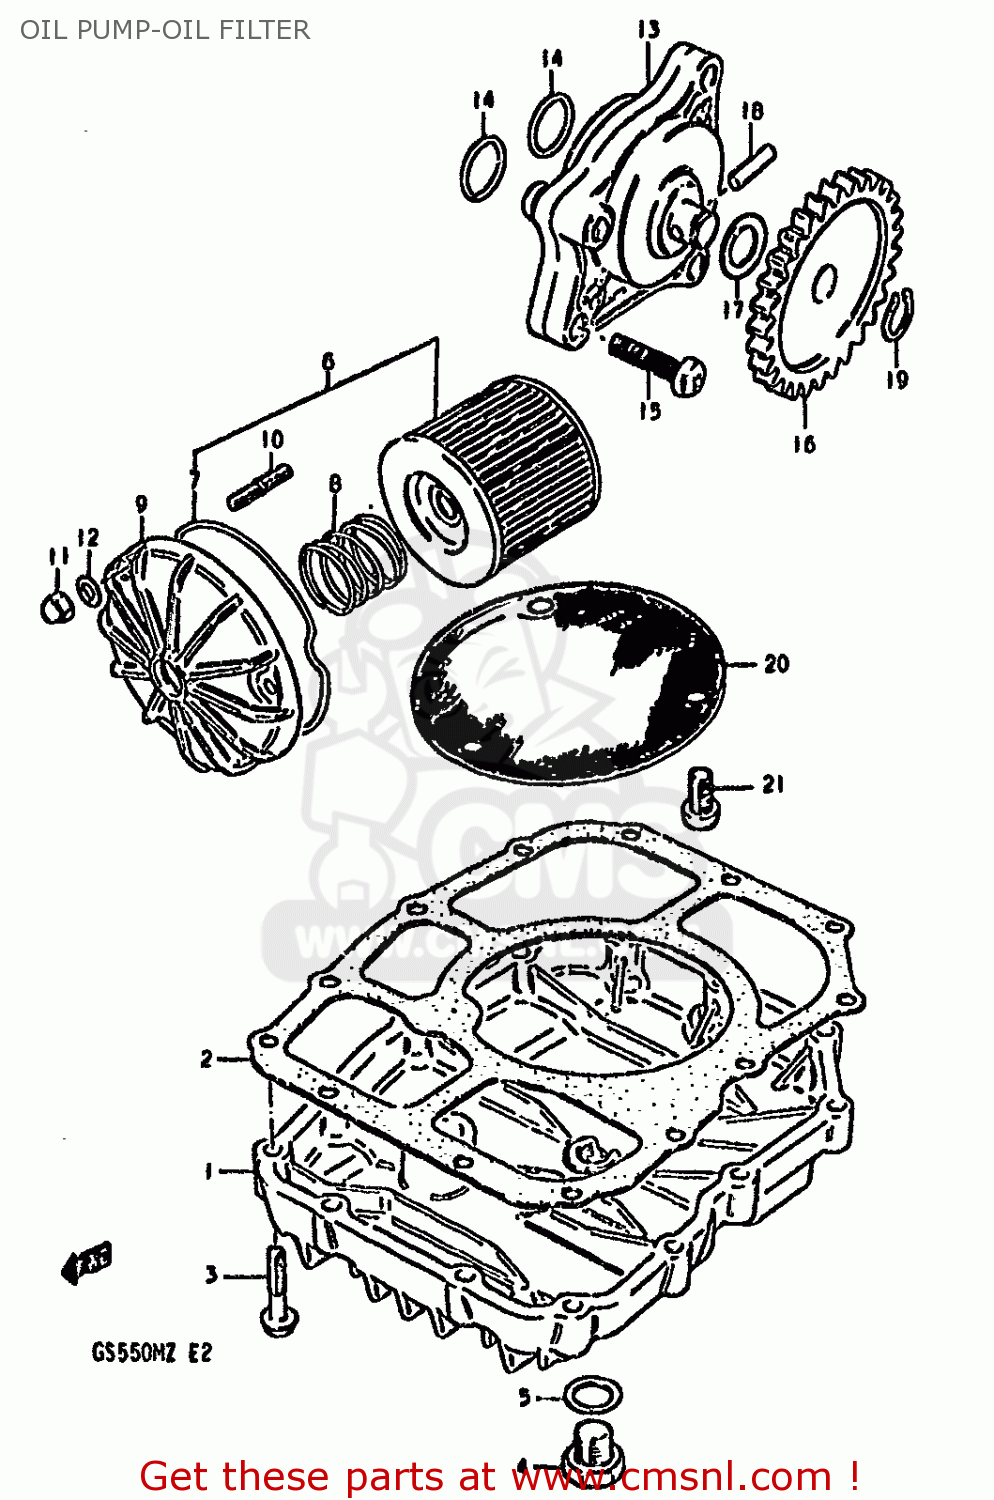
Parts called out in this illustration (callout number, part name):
1	PAN,OIL
2	GASKET,OIL PAN (MCA)
3	BOLT
4	PLUG
5	GASKET(14X19.2X2) (NAS)
6	ENGINE OIL FILTER SET
7	O RING,OIL FILTER CHAMBER CAP
8	SPRING
9	CAP,ENGINE OIL FILTER
10	STUD 6X20
11	NUT
12	WASHER
13	PUMP ASSEMBLY,ENGINE OIL
14	O RING(D:1.9,ID:13)
15	SCREW
16	GEAR,OIL PUMP DRIVEN
17	SHIM
18	PIN(4X15.8)
19	CIRCLIP
20	STRAINER,ENGINE OIL
21	SCREW 6X12
